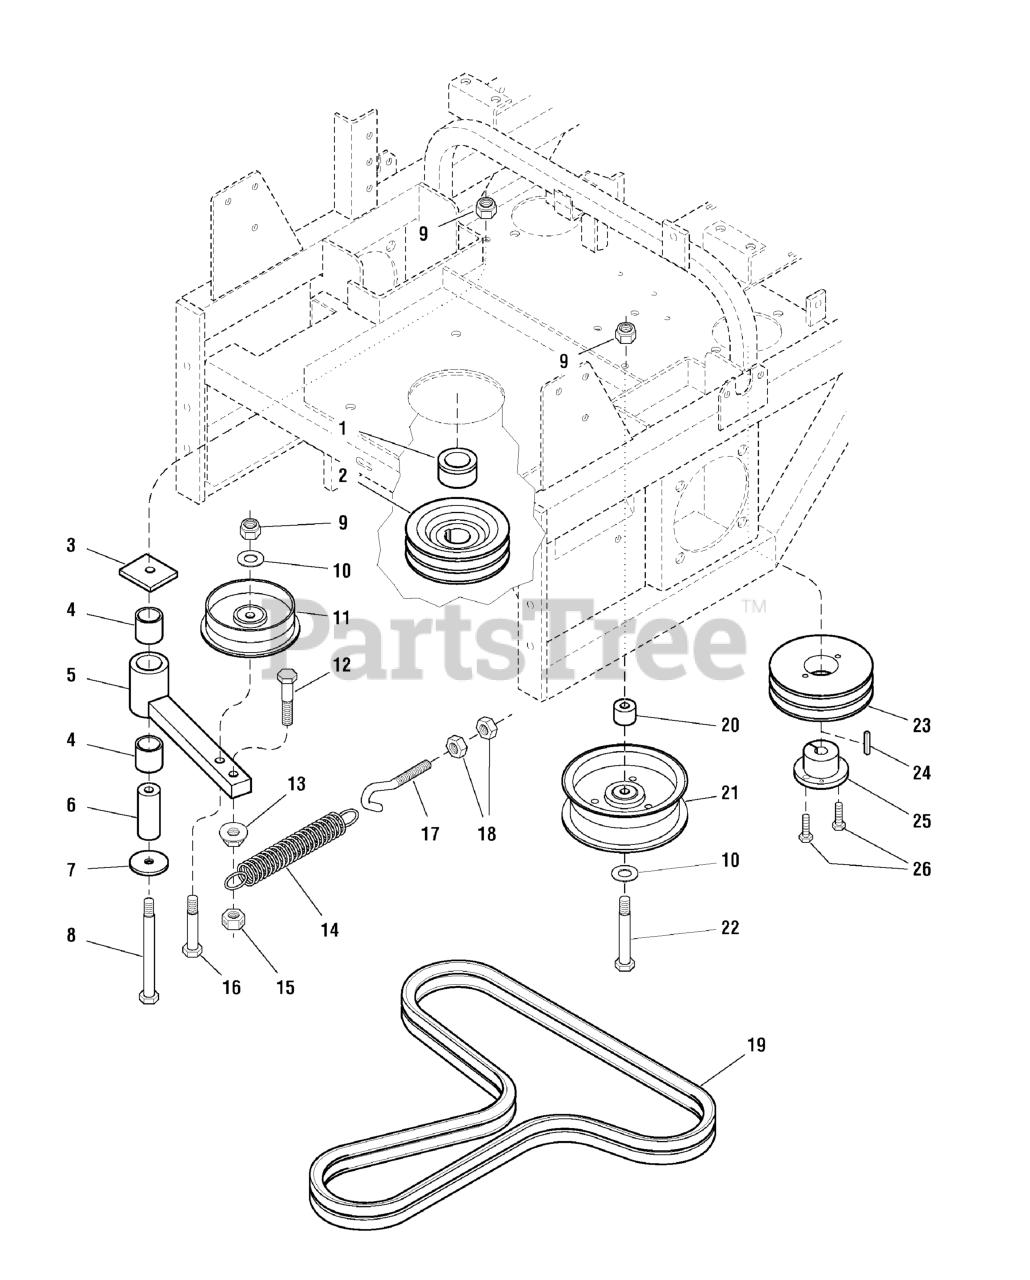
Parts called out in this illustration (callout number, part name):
1	SPACER, 1.13 x 1.75 x 1.03
2	CRANKSHAFT PULLEY
3	SPACER, Idler Pivot
4	BUSHING, Brass
5	WELD, ARM, PUMP DRIVE IDLER - BLK
6	SPACER, .39 X 1.00 X 2.55, SS
7	WASHER, 3/8 x 1-3/4
8	BOLT, 3/8-16 X 4" GD5 CZ
9	NUT, 3/8-16 HEX NYLON LOCK
10	WASHER, 3/8 SAE
11	PULLEY, Idler (Single Flange)
12	BOLT, 3/8-16 X 1-3/4" GD5 CZ
13	NUT, 3/8-16 Hex Serrated Flange
14	SPRING, Extension, Swivel End
15	NUT, 3/8-16 Hex Side Lock
16	BOLT, 3/8-16 X 2-1/4" GD5 CZ
17	SCREW HOOK, 3/8-16 x 4-1/4
18	NUT, 3/8-16 Hex
19	BELT, Pump Drive (set of 2)
20	SPACER, .39 x 1.00 x .79
21	PULLEY, Idler
22	BOLT, 3/8-16 X 2-3/4" GD5 CZ
23	PULLEY, Pump Drive
24	KEY, 5MM SQ. x 25MM w/ Round Ends
25	BUSHING, Tapered Hub
26	BOLT, 1/4-20 X 1" GD5 CZ
